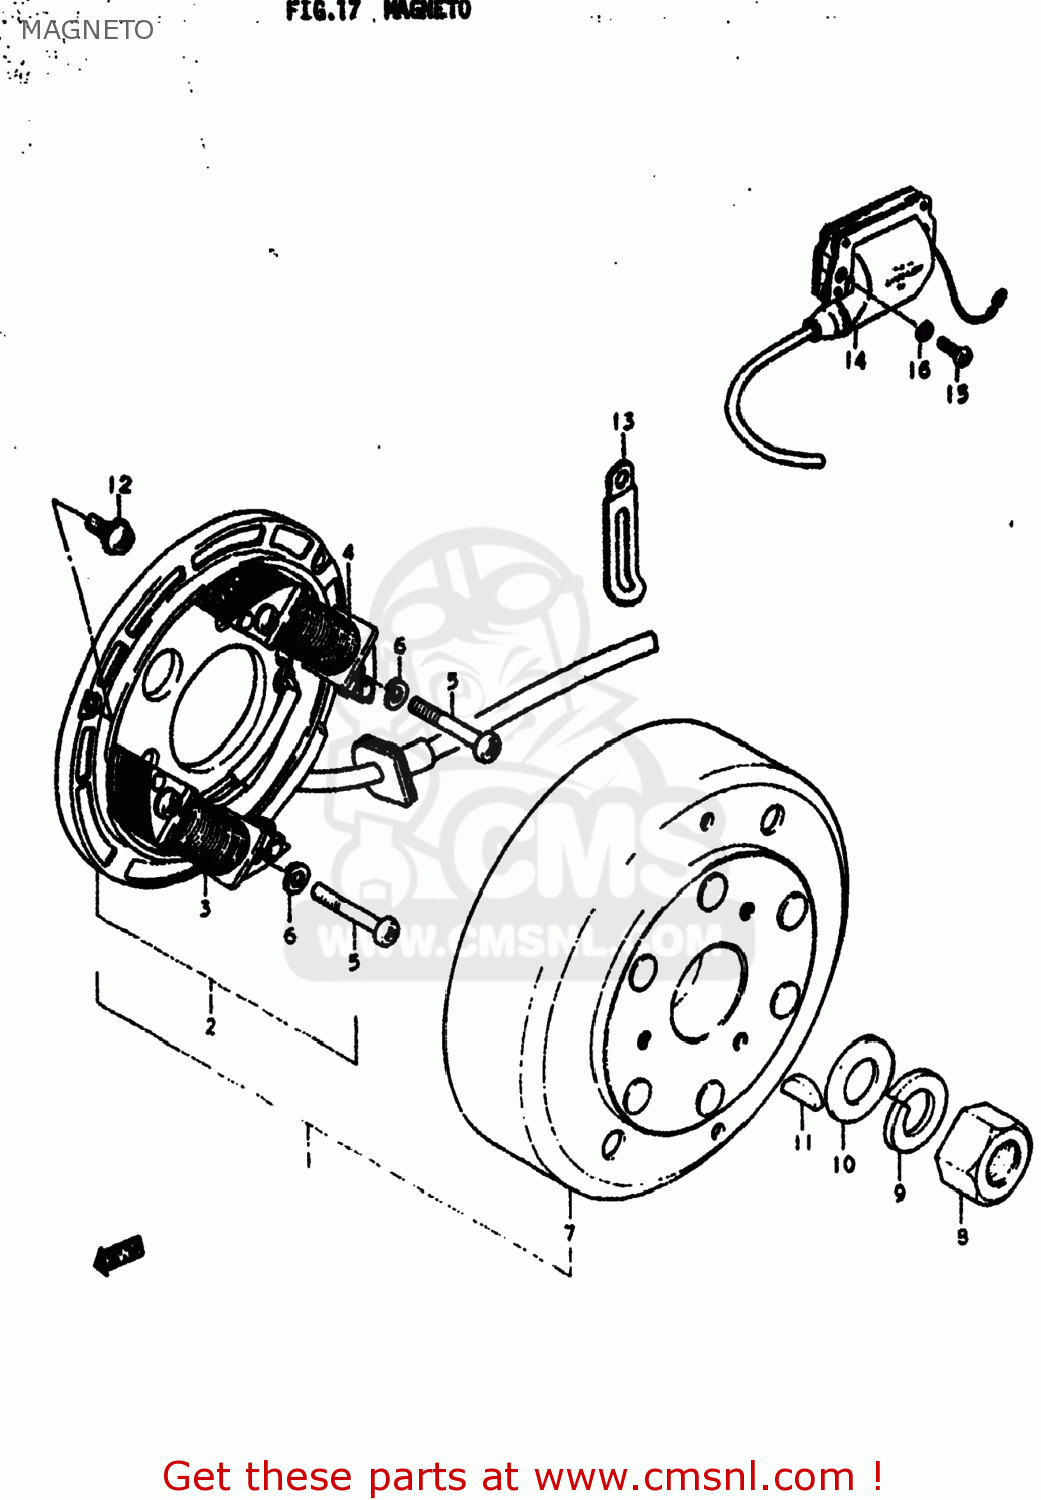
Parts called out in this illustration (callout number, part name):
1	MAGNETO ASSEMBLY
2	STATOR ASSEMBLY
3	COIL,LIGHTING
4	COIL,PRIMARY
5	SCREW
6	LOCK WASHER
7	ROTOR ASSEMBLY
8	NUT
9	LOCK WASHER
10	WASHER(14X27X3)
11	KEY 4MM
12	SCREW(5X14)
13	CLAMP
14	COIL ASSEMBLY,IGNITION
15	SCREW
16	LOCK WASHER
